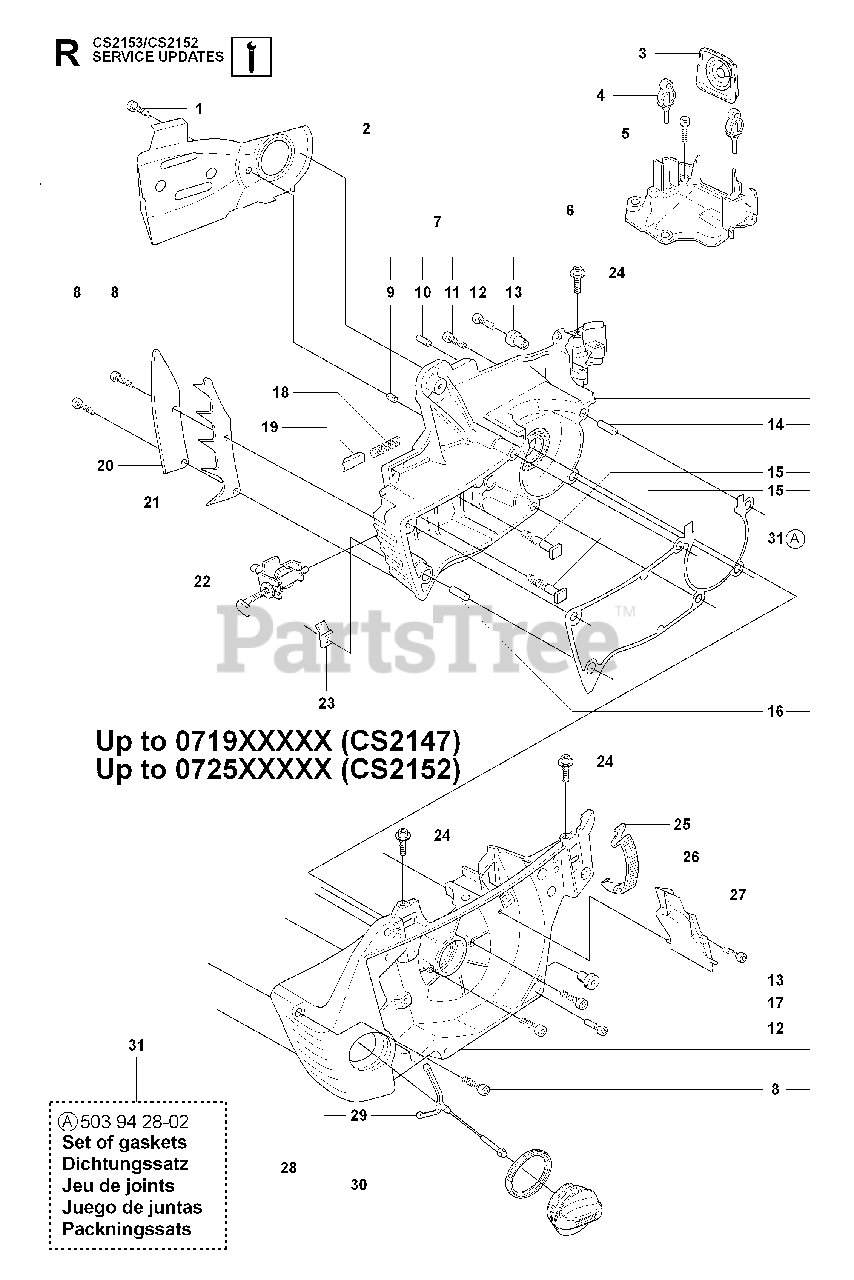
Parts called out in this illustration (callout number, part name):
7	CRANKCASE ASSY.
13	MOVEMENT LIMITER
18	LOCK SPRING
21	FELLING DOG
22	CHAIN TENSIONER
23	CHAIN CATCHER
26	DEFLECTOR
30	OILCAP GASKET
31	GASKET SET
